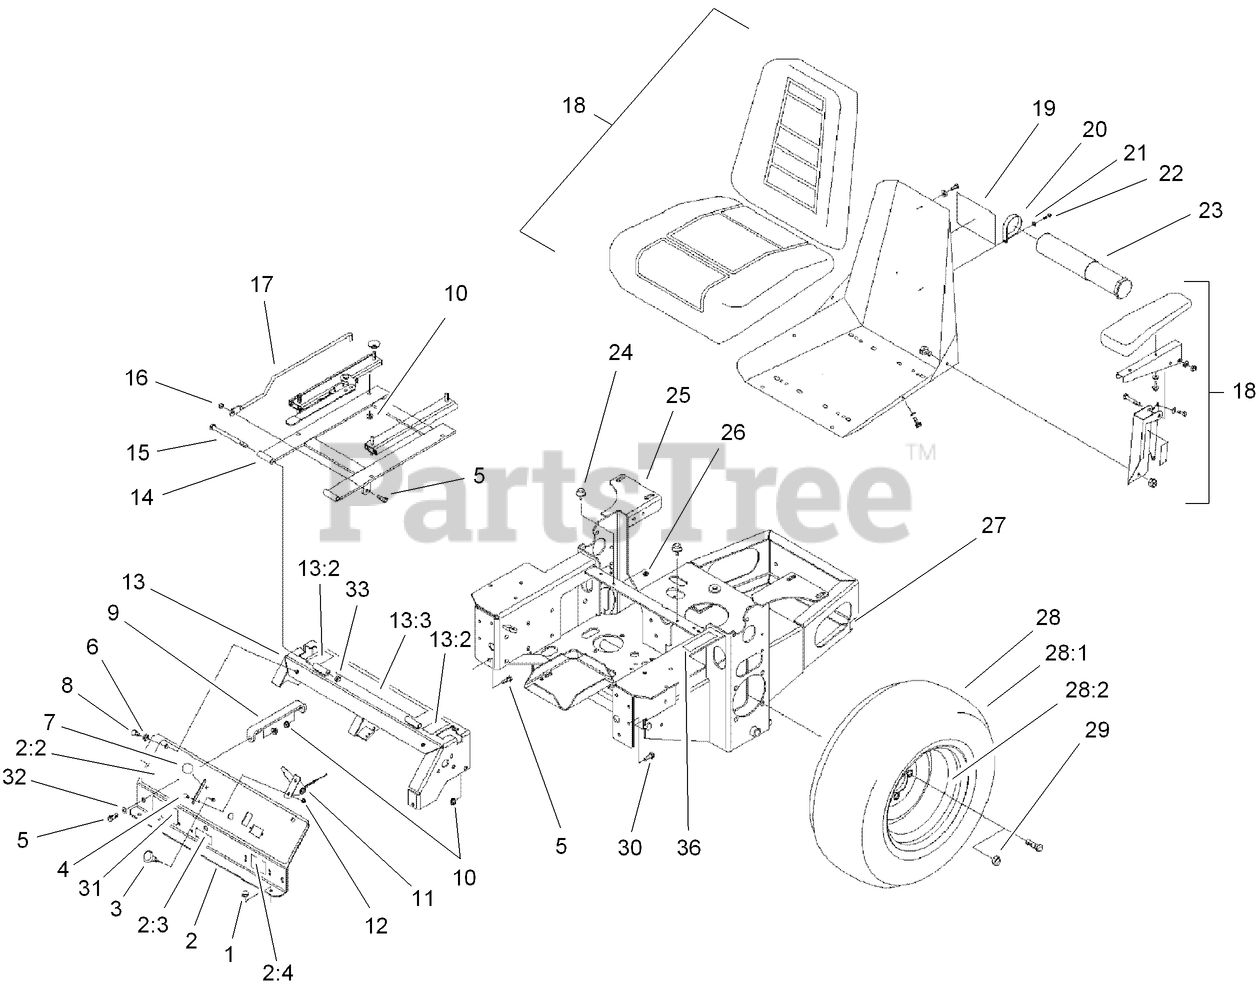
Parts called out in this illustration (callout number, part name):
1	Bumper
2	CONTROL PANEL ASM
2:2	DECAL-PANEL, CONTROL
2:3	Decal-Fuel Valve
2:4	DECAL-PROTECTION, EAR
3	Cable-Choke
4	Bolt-CARR
5	SCREW-HH
6	WASHER-PLAIN
7	Knob
8	SCREW-HH
9	Bracket-Panel,Instrument
10	NUT-HF
11	Cable
12	NUT-LOCK, NI
13	CONSOLE ASM
13:2	Decal-Motion Control
13:3	Decal-Battery
14	Frame-Seat
15	SCREW-HH
16	NUT-LOCK, NI
17	Rod-Hold Up, Seat
18	SEAT ASM
19	DECAL
20	CLAMP-R
21	WASHER-FLAT
22	SCREW-HWHTF
23	TUBE-MANUAL
24	Bumper
25	Frame-Engine Deck
26	NUT-HF
27	DECAL-SURFACE, HOT
28	Wheel And Tire ASM
28:1	Tire
28:2	Wheel
29	Nut
29	Wheel Bolt
30	SCREW-HH
31	DECAL-Z147
32	WASHER-FLAT
33	NUT-LOCK, NI
36	Decal-Drive Wheel
